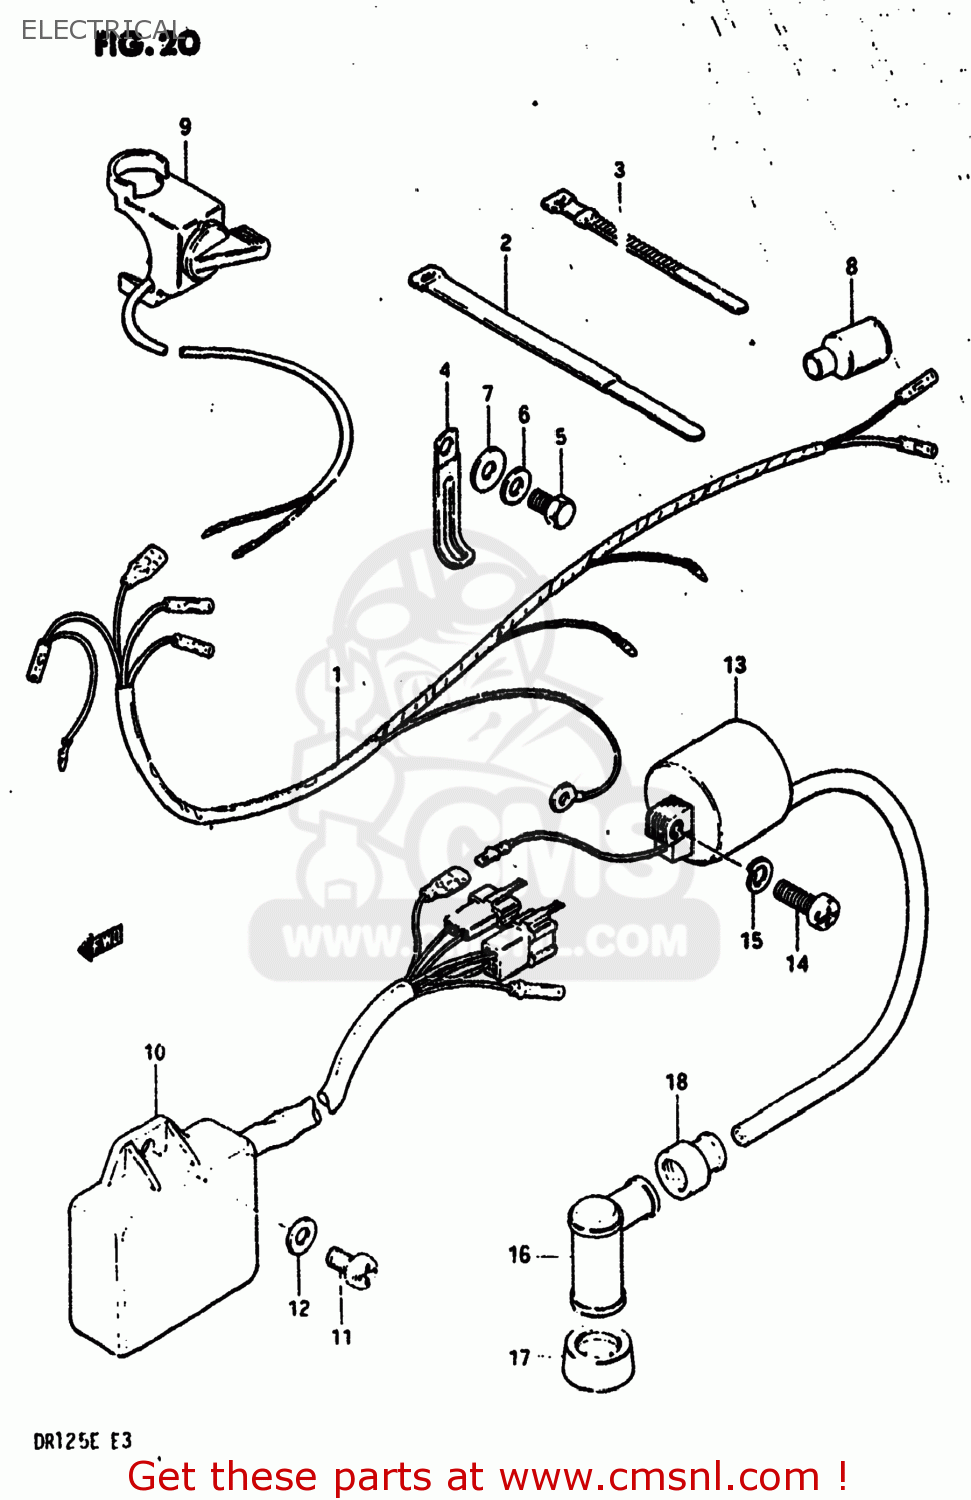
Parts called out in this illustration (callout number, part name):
1	HARNESS,WIRING
2	CLAMP
3	CLAMP(L:120)
4	CLAMP
5	BOLT 6X16
6	WASHER
7	WASHER
8	BOOT,WIRING HARNESS
9	SWITCH ASSY,ENGINE STOP
10	CDI UNIT
11	SCREW
12	WASHER
13	COIL ASSEMBLY,IGNITION
14	SCREW
15	LOCK WASHER
16	CAP ASSY,SPARK PLUG
17	SEAL,SPARK PLUG
18	SEAL,SPARK PLU
